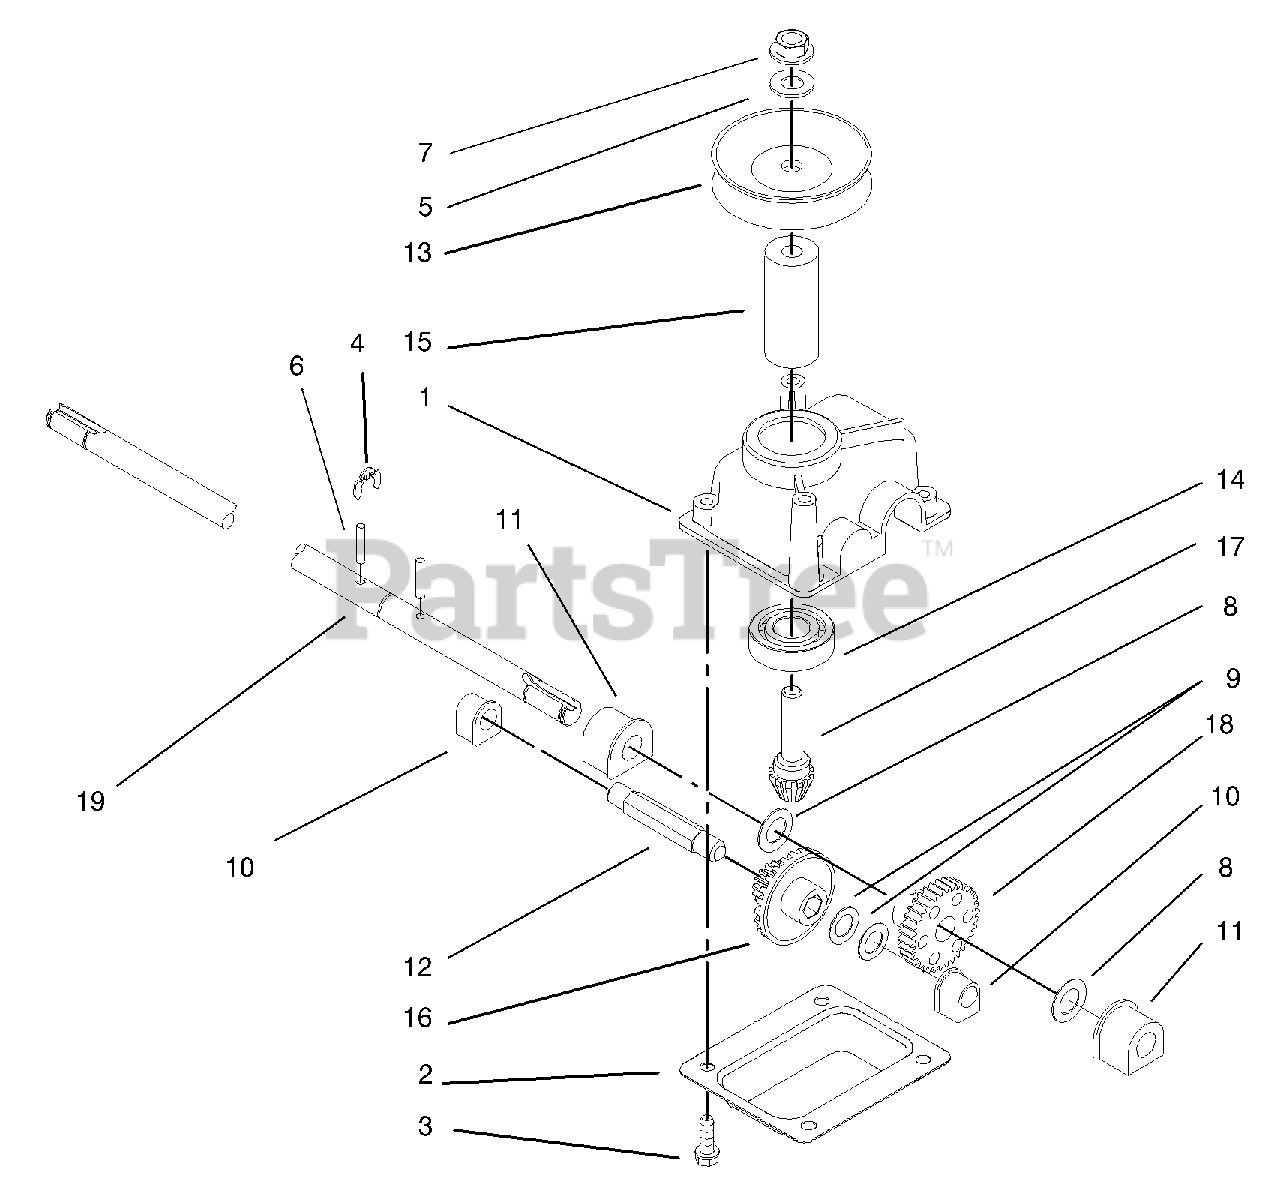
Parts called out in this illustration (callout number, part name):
1	CASE-GEAR
2	COVER-CASE, GEAR
3	SCREW-HWH
4	RING-RETAINING
5	WASHER-FLAT
6	PIN-GROOVE
7	NUT-LOCK, NI
9	WASHER-THRUST
12	SHAFT-INTERMEDIATE
13	HALF-PULLEY
14	BEARING-BALL
15	SPACER-PULLEY
16	GEAR-15T SPUR, 37T BEVEL
17	GEAR-PINION,BEVEL
19	SHAFT-OUTPUT
